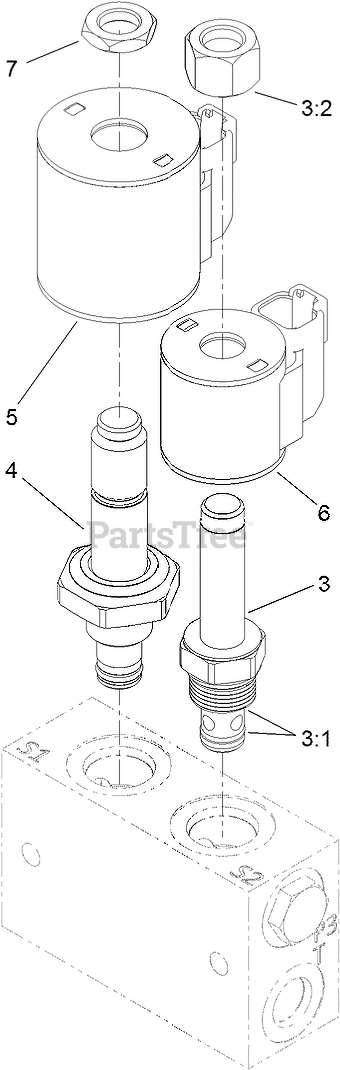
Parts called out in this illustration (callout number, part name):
3	VALVE-SOLENOID
3:1	SEAL KIT
3:2	NUT-SOLENOID
4	VALVE-SOLENOID
5	COIL-12V
7	NUT-COIL
